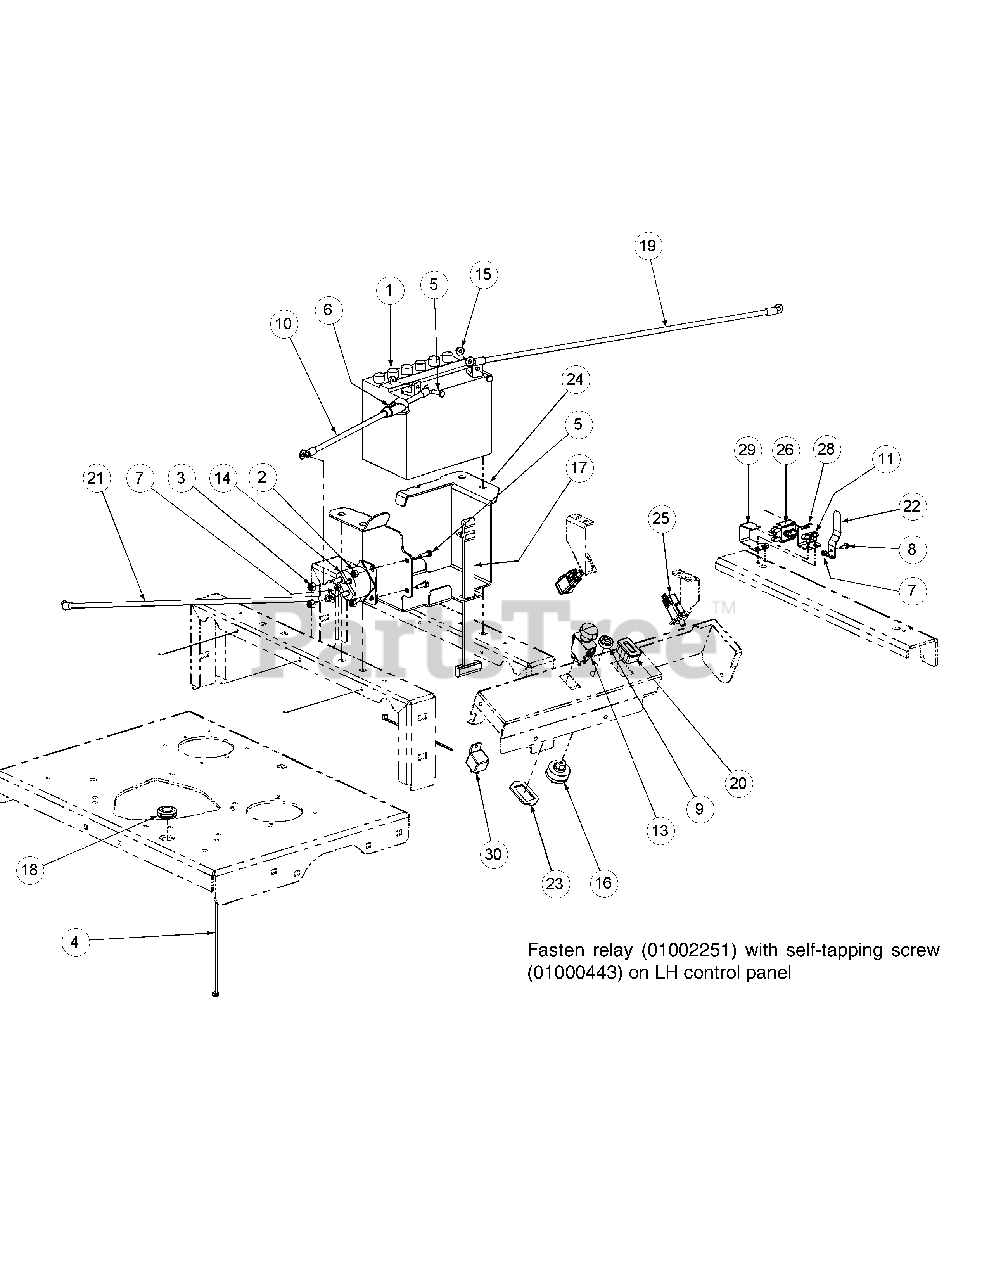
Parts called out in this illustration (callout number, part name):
1	Battery, 12V 225CCA 30 Min
2	Lock Nut w/Nylon Insert
3	Nylock Nut, 5/16-18
4	Tie, Cable, 3/16 x .05 x 7.4"
5	Screw, Hex, Cap, 1/4-20 x .75
6	Boot, 1" OD Rubber Battery-PST, Red
7	Nut, Lock, Nylon Insert, #10-32
8	Screw, Hex Washer, 10-32 x 1/2
9	Nut, W/Cap, 5/8-32 Ignition
10	Cable, Battery, Red, 15"
11	Screw, TT, 1/4-20, 0.5, Hex Index Washer
13	Switch, Electric, PTO
14	Solenoid Magnetic Switch
15	Hex Flange Lock Nut, 1/4-20
16	Switch, Ignition, 6 Pin
17	Strap, Battery
18	Grommet, .75 ID
19	Cable, Battery Black, 28"
20	Meter, Hour
21	Cable, Battery Red, 32"
22	Spring Retainer
23	Bracket, PTO Switch Retainer
24	Mount Bracket, Battery
25	Switch, Safety N.O./N.C.
26	Switch, Plunger
28	Bracket, Plunger Switch
29	Clamp, Plunger Switch
30	Relay, 12V 40A
